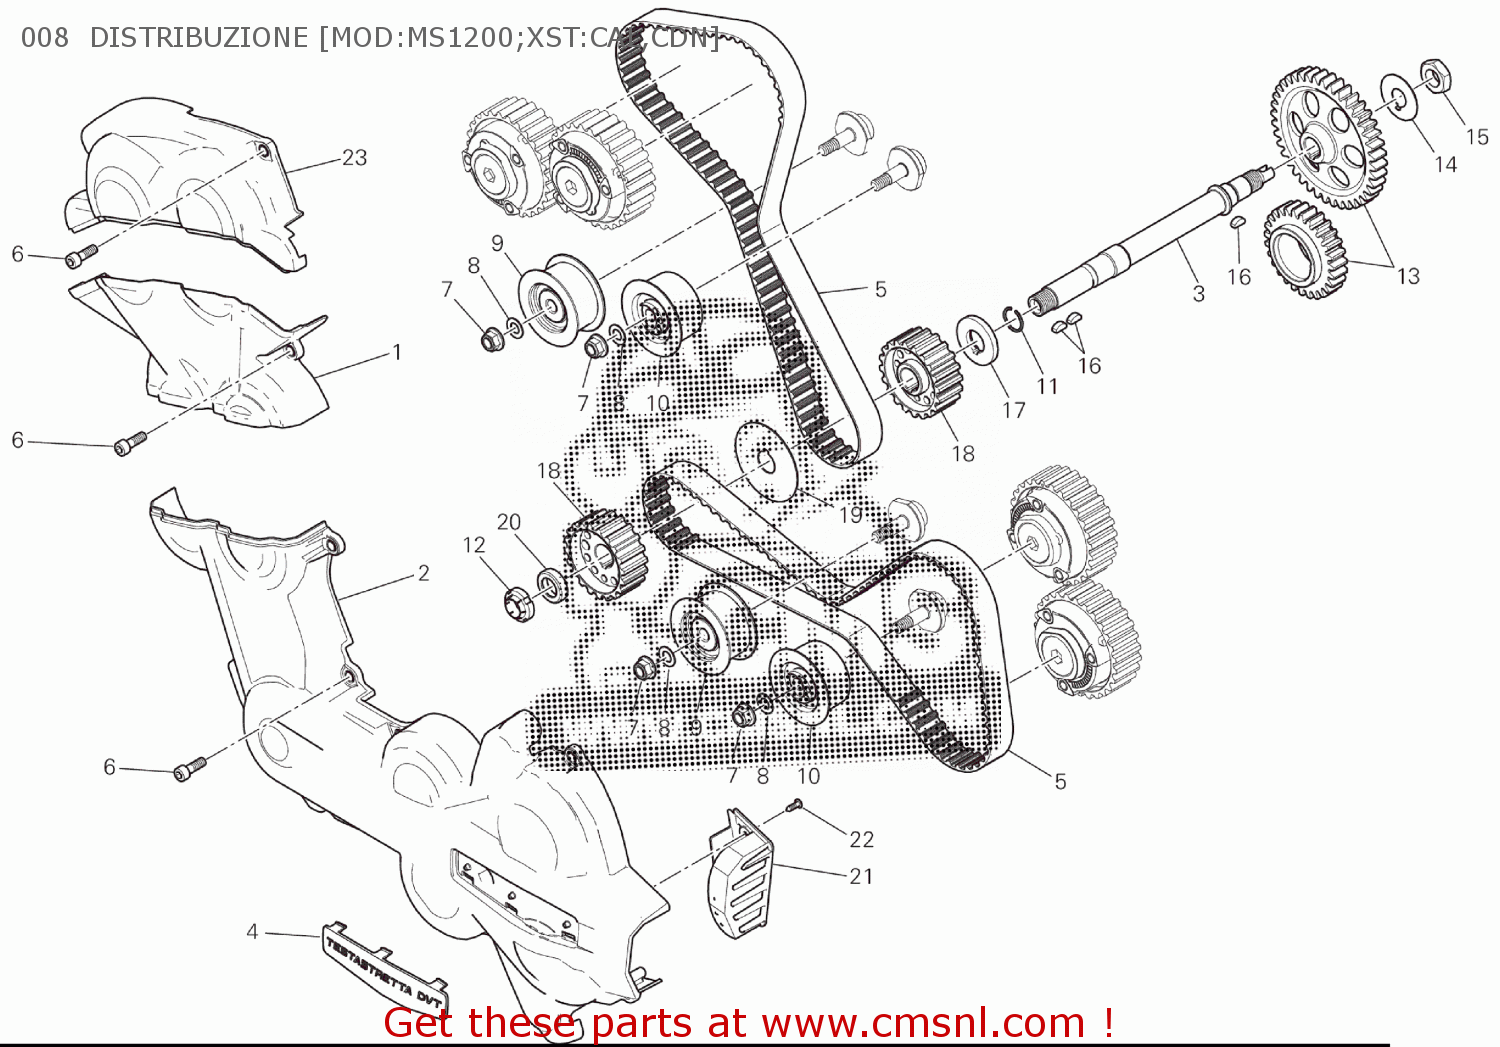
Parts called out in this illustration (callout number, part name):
1	VERTICAL BELT OUTER COVER BOTTOM
2	HORIZONTAL BELT EXTERNAL COVER
3	LAYSHAFT TIMING
4	MARKING PLATE
5	TIMING DRIVE TOOTHED BELT
6	SCREW
7	NUT M8
8	SPRING WASHER 8 MM
9	TENSIONER TIMING BELT FIXED
10	COMPLETE MOVABLE TENSIONER ROLLER
11	SNAP RING
12	ELASTIC-STOP RING NUT
13	TIMING GEARS SET
14	WASHER, LOCK
15	NUT M14X1X7
16	KEY, WOODRUFF 4X5X10
17	SPACER
18	PULLEY, TIMING BELT
19	WASHER, BELT PULLEY
20	SPACER
21	BRACKET, FILTER
22	SCREW
23	COVER, TIMING BELT INSIDE
